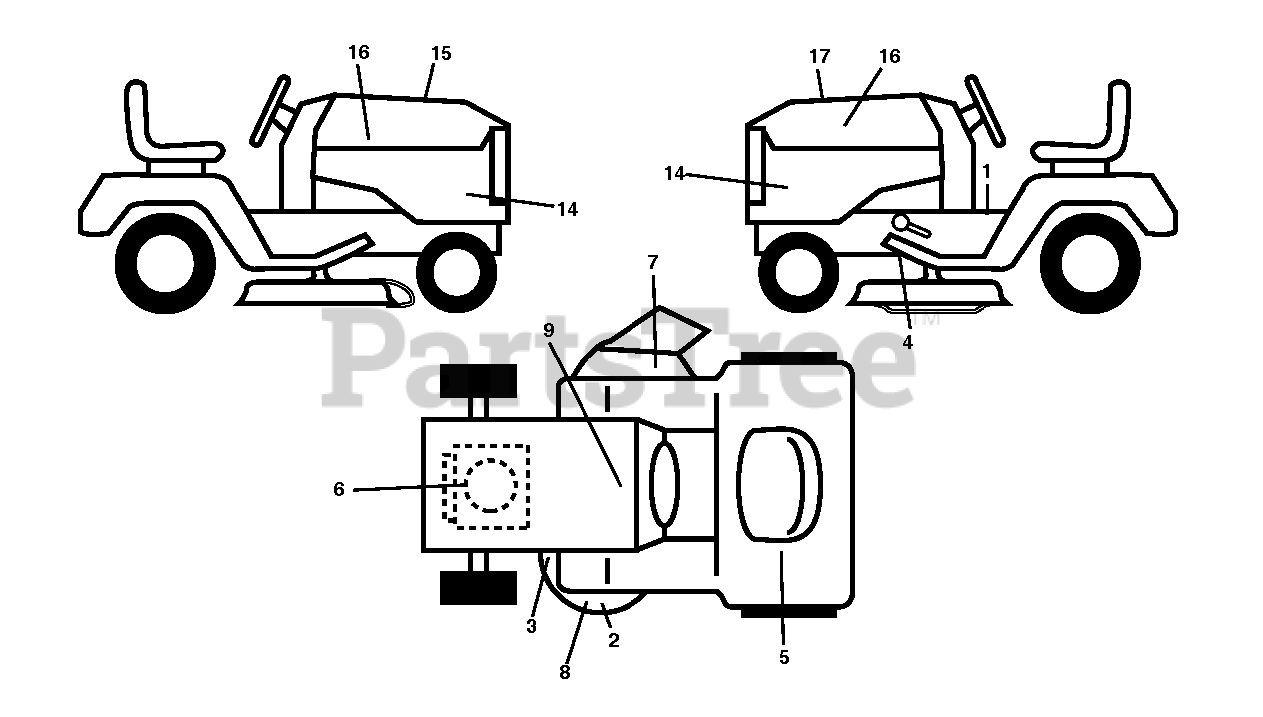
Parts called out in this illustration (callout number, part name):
1	DECAL.FNDR.WARN.SMARTIGN.
2	DECAL.DECK.6MIL.EURO.NOSTEP
3	DECAL.MOWER.SCH.48/54.PREM
4	DECAL.PEDAL.HUSQ.CROWN
5	DECAL.RESERVEFUELSELCTR.ENG
6	DECAL.ENG.BS.ENDUR.24HP.382021
7	DECAL, DECK DEFLECTOR, WARNING
8	DECAL.HV.REINFORCED.DECKS.2012
9	DECAL BTRY SYMBOLS
14	DECAL SIDE PANEL
15	DECAL.WARNING.CUST.RESP.E85.
16	DECAL.BADGE.170MM.TEXTLOGO.
17	DECAL.RPL.BSM44.ENDUR.TGB.52F
